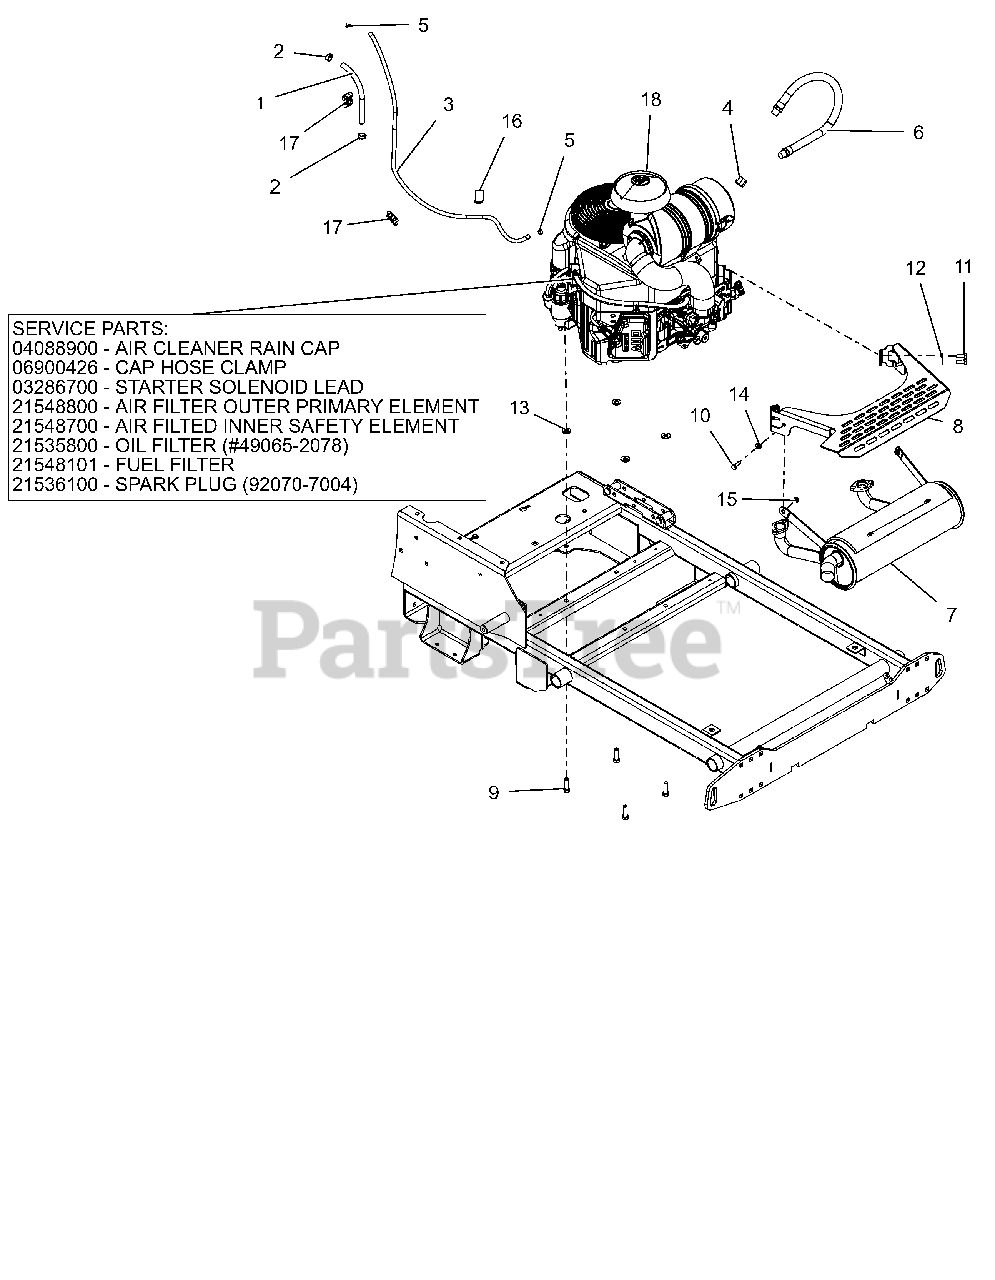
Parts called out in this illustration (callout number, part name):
1	HOSE, .25 LOW-PERM BULK GAS
2	CLAMP, FUEL LINE
3	HOSE, .188 LOW-PERM BULK GAS
4	PIPE CAP 3/8 NPT FEMALE
5	CLAMP-HOSE, SPRING .188
6	DRAIN, M20 OIL
7	EXHAUST, KAWASAKI PROSTANCE
8	SHIELD, MUFFLER
9	BLT-HEX.38-16X1.25 G5YZ NYTORQ
10	@BLT-HEX .25-20X1.00 GR5 YWZC
11	@BLT-HEX M8-1.25X20 YWZC
12	@WSHR-LK .31X.078 REG YWZC
13	WASHER, 3/8" SPRING DISC
14	@WSHR-FL-STL.281X.62X.065 YWZC
15	@NUT-LK-NYL-FLG .25-20 YWZC
16	CLAMP, COUSHIONED STEEL REV
17	CLIP, T, .38-.50
18	ENGINE, KAWASAKI FX730
18	CAP, KAW 11065-7025
18	CLAMP, HOSE #36 SS 1.813-2.75
18	LEAD - STARTER SOLENOID
18	FILTER, OUTER
18	FILTER, INNER - KAW
18	FILTER,OIL - KAW
18	FUEL FILTER-KAWASAKI FR
18	PLUG, SPARK
